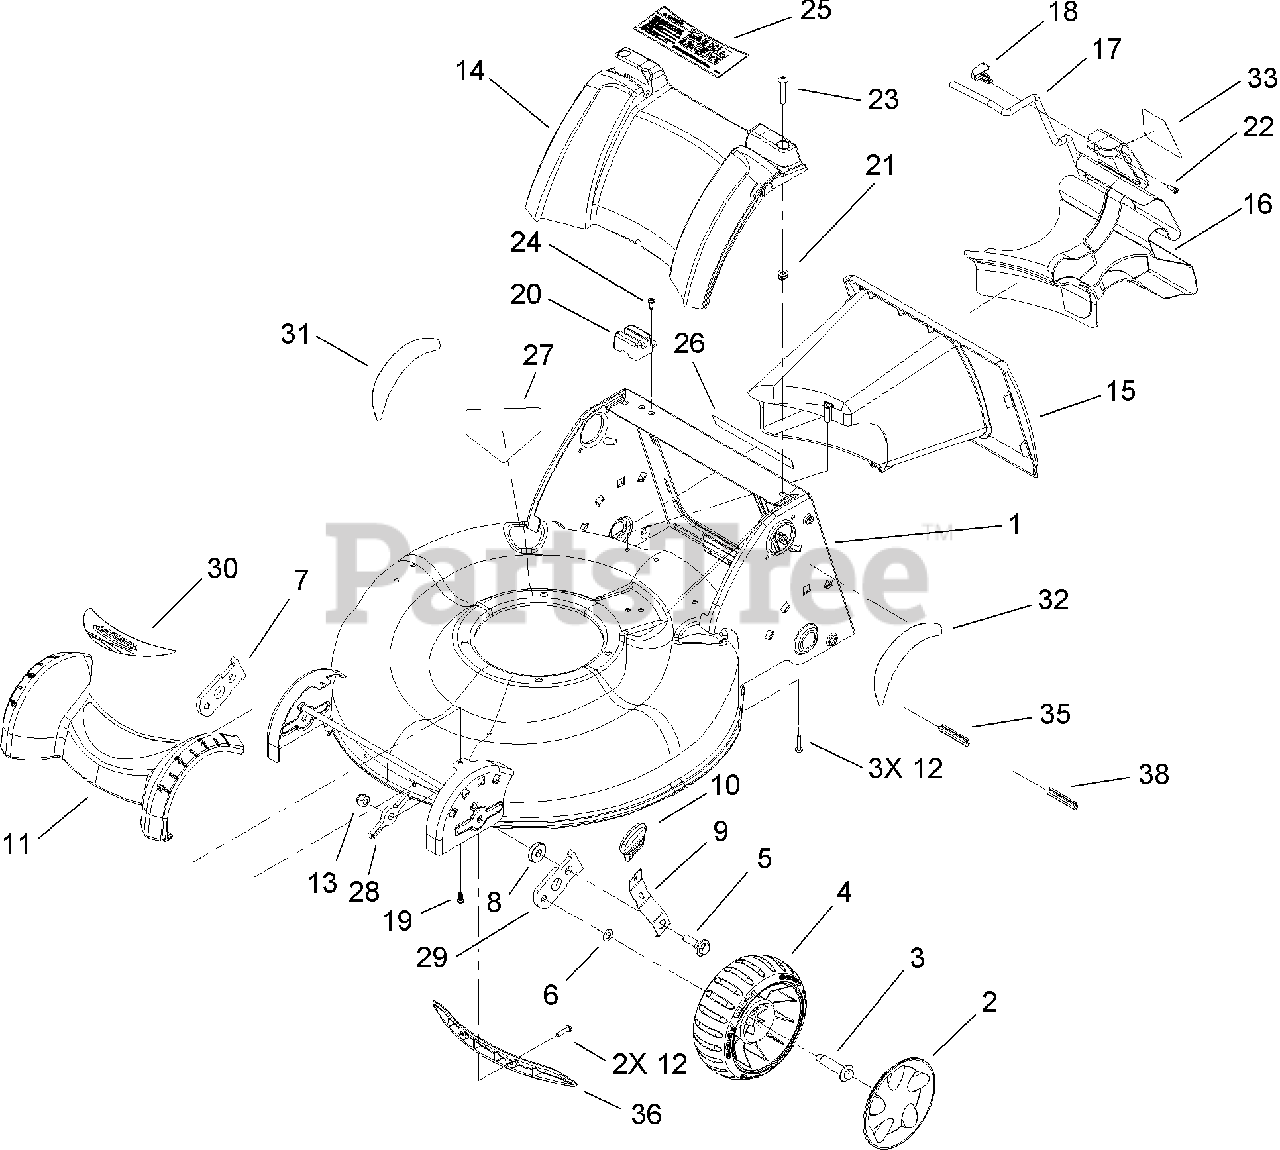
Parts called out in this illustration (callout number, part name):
1	HOUSING ASM
2	COVER-WHEEL, 7IN
3	BOLT-SHOULDER
4	7IN WHEEL ASM
5	BOLT-SHOULDER
7	ARM-PIVOT, RH
9	ARM-SPRING
10	KNOB-LEVER, HOC
11	COVER-FRONT
12	SCREW-PLASTITE
13	NUT-LOCK, NI
14	COVER-REAR
15	TUNNEL
16	PLUG-CHUTE
17	LATCH-PLUG
18	RETAINER-LATCH
19	SCREW-PLASTITE
20	MODULE-SWITCH
21	NUT-CLIP
22	SCREW-PPH
23	SCREW-PTH
24	SCREW-THREAD FORMING
25	DECAL-DANGER
26	DECAL-SAFETY
27	DECAL-DANGER
28	WASHER-SUPPORT, FRONT
29	ARM-PIVOT, LH
31	DECAL-HOC, RH
32	DECAL-HOC, LH
35	STRIP-EDGE
36	INSERT-HOUSING
38	STRIP-EDGE
